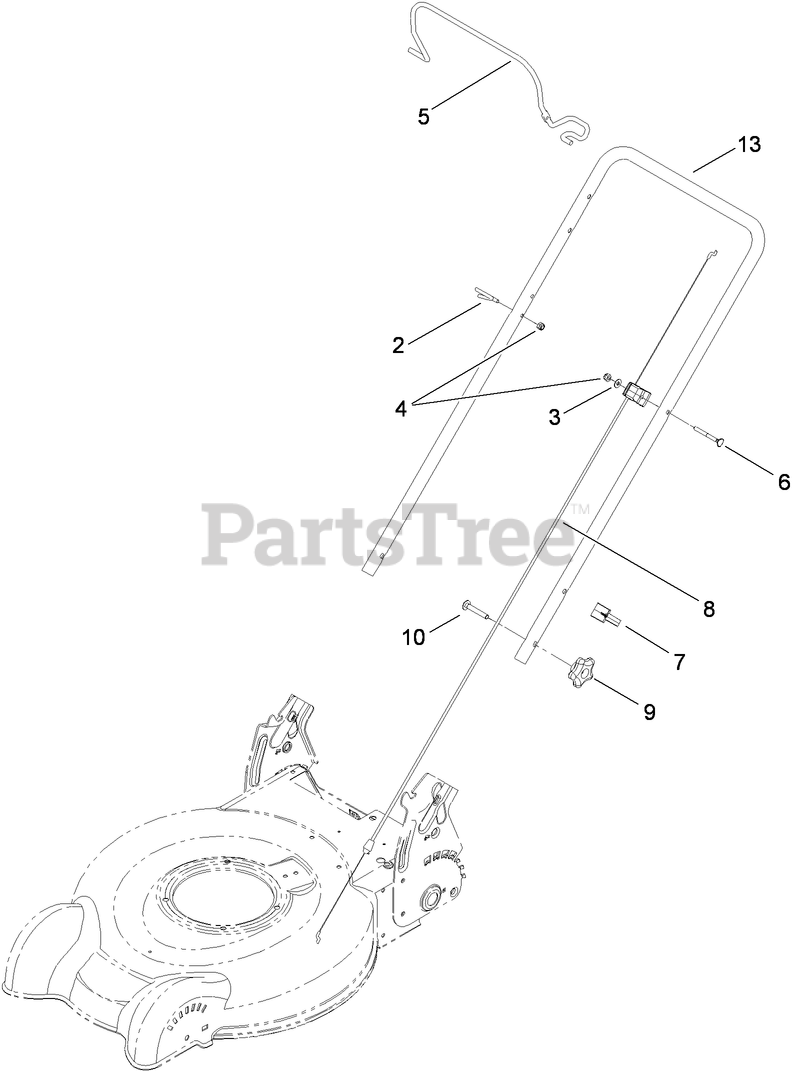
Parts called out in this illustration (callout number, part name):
2	GUIDE-ROPE
3	WASHER-FLAT
4	NUT-LOCK, NI
5	BAIL-BRAKE
6	SCREW-HANDLE
7	GUIDE-CABLE
8	CABLE-BRAKE
9	KNOB-HANDLE
10	BOLT-CARR
13	HANDLE-UPPER
